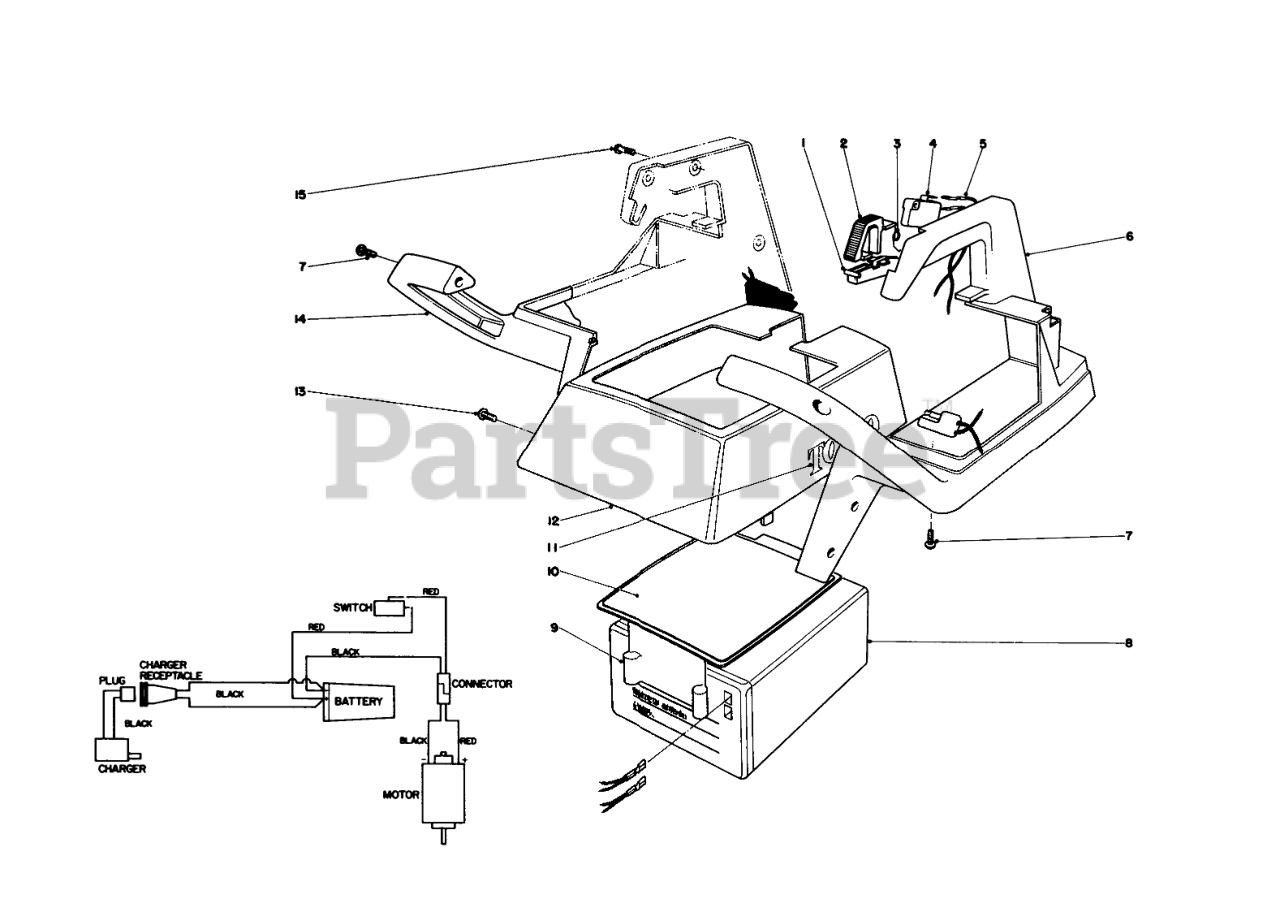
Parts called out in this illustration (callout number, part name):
1	TRIGGER
2	TRIGGER LOCK
3	SPRING
4	Switch
5	Upper Wiring Harness
6	Left Hand Case
7	Screw
8	BATTERY
9	CONTROL PANEL, CL-710
10	Decal, Control Panel
11	DECAL - TORO
12	Cover
13	10-16 X .31 SCREW
14	Right Hand Case
15	SCREW-PPH
